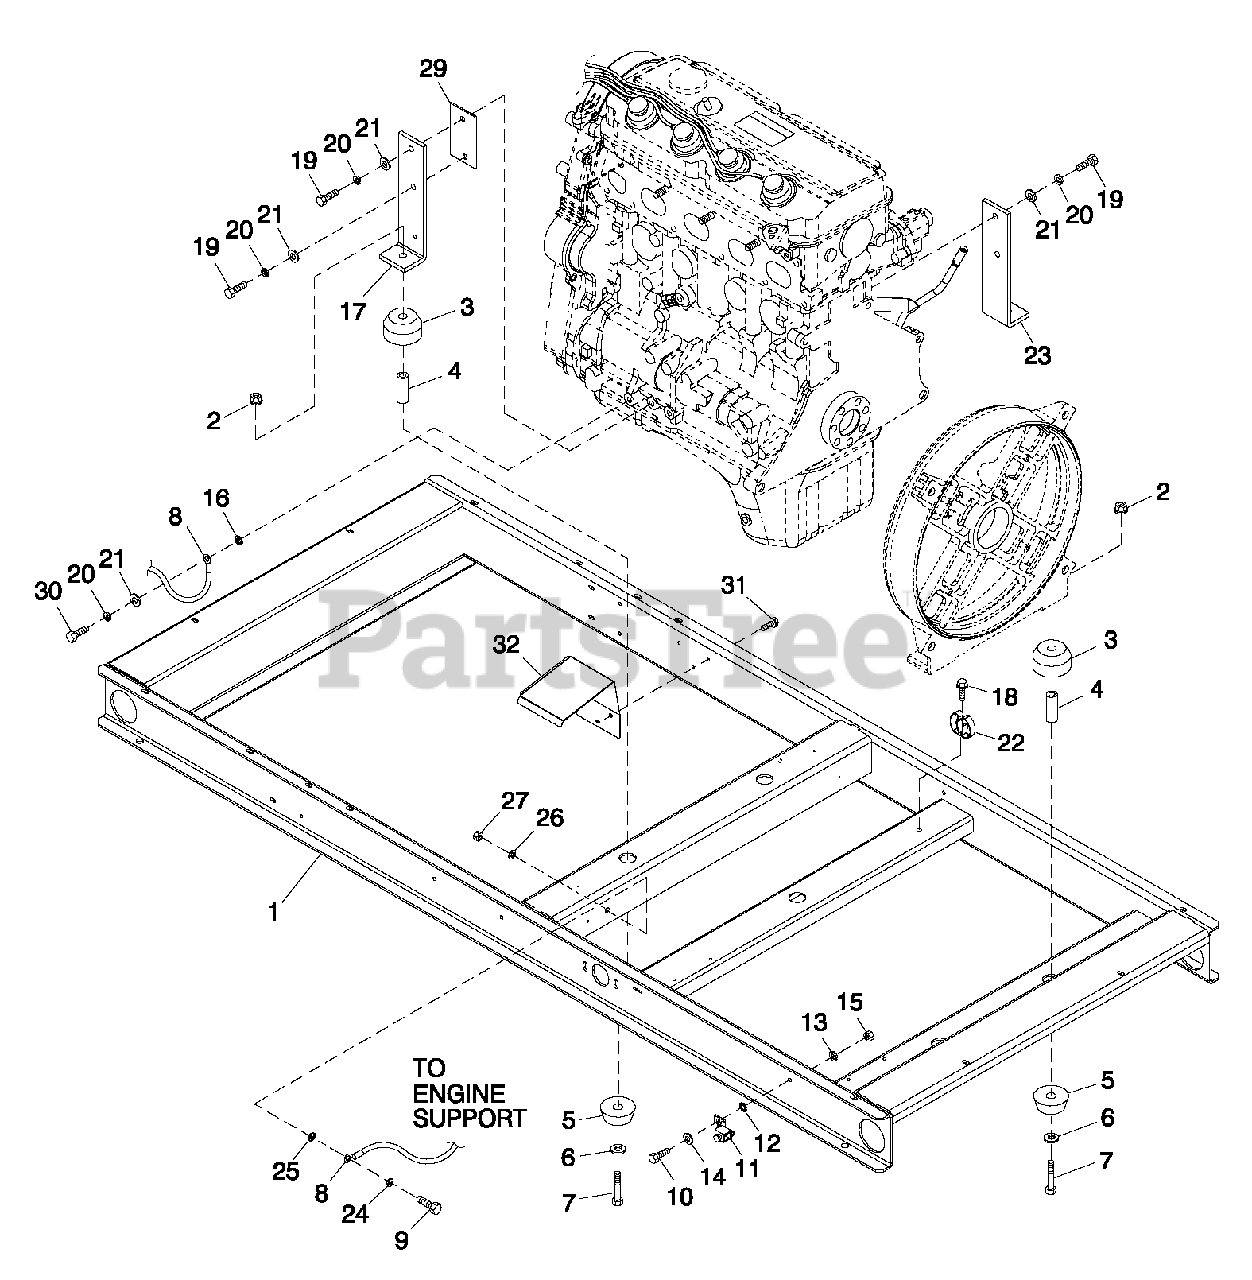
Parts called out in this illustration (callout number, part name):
1	WELDMENT FRAME 2.4L C2
2	NUT FLANGED HEX M12-1.75
3	DAMPENER VI B RATION 40 BLUE
4	SPACER .49 X .62 X 1.87 PWDR/ZNC
5	DAMPENER VI B RATION
6	WASHER FLAT M12
7	SCREW HHC M12-1.75 X 80 G8.8
8	ASSY WIRE 14.00"
9	SCREW HHC M8-1.25X 30 G8.8
10	SCREW HHC M6-1.0X 16 G8.8
11	LUG SLDLSS #2-#8X 17/64 CU
12	WASHER LOCK SPECIAL 1/4"
13	WASHER LOCK M6-1/4
14	WASHER FLAT M6-1/4 ZINC
15	NUT HEX M6 -1.0G8YEL CHR
16	WASHER SHAKEPROOF INT 3/8
17	SUPPORT LH ENGINE 2.4L
18	SCREW HHTT M4-0.7X8BP
19	SCREW HHC M10-1.25 X 30 G8.8
20	WASHER LOCK 7/16
21	WASHER FLAT 3/8-M10 ZINC
22	SPRING CLIP HOLDER .37-.62
23	SUPPORT RH ENGINE 2.4L
24	WASHER LOCK M8-5/16
25	WASHER LOCK SPECIAL 5/16
26	WASHER FLAT 5/16-M8 ZINC
27	NUT HEX M8-1.25 G8 CLEAR ZINC
29	SPACER ENGINE MOUNT (2.4L G1)
30	SCREW HHC M10-1.25 X 25 C8.8
31	SCREW HWHT M6-1 X 16 N WA Z/JS
32	HEAT SHIELD 2.4L G2
